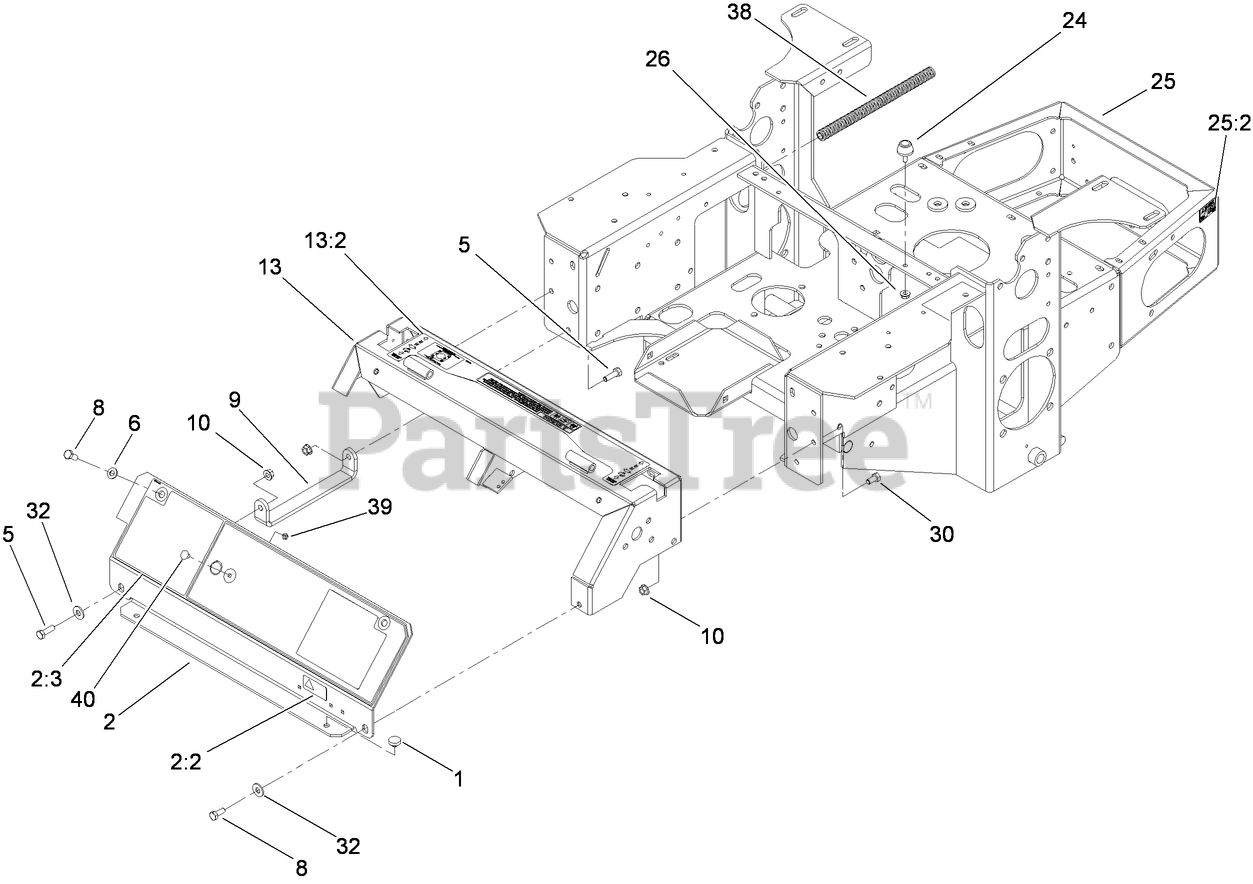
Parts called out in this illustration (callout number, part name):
1	BUMPER
2	PANEL ASM
2:2	DECAL-PROTECTION, EAR
2:3	DECAL-COVER, PANEL
5	SCREW-HH
6	WASHER-PLAIN
8	SCREW-HH
9	BRACKET-PANEL, INSTRUMENT
10	NUT-HF
13	CONSOLE ASM
13:2	DECAL-WARNING
24	BUMPER-RUBBER
25	MAIN FRAME ASM
25:2	DECAL-SURFACE, HOT
26	NUT-HF
30	SCREW-HH
32	WASHER-FLAT
38	CONDUIT-CONVOLUTED, SPLIT
39	NUT-LOCK, NI
40	BOLT-CARR
